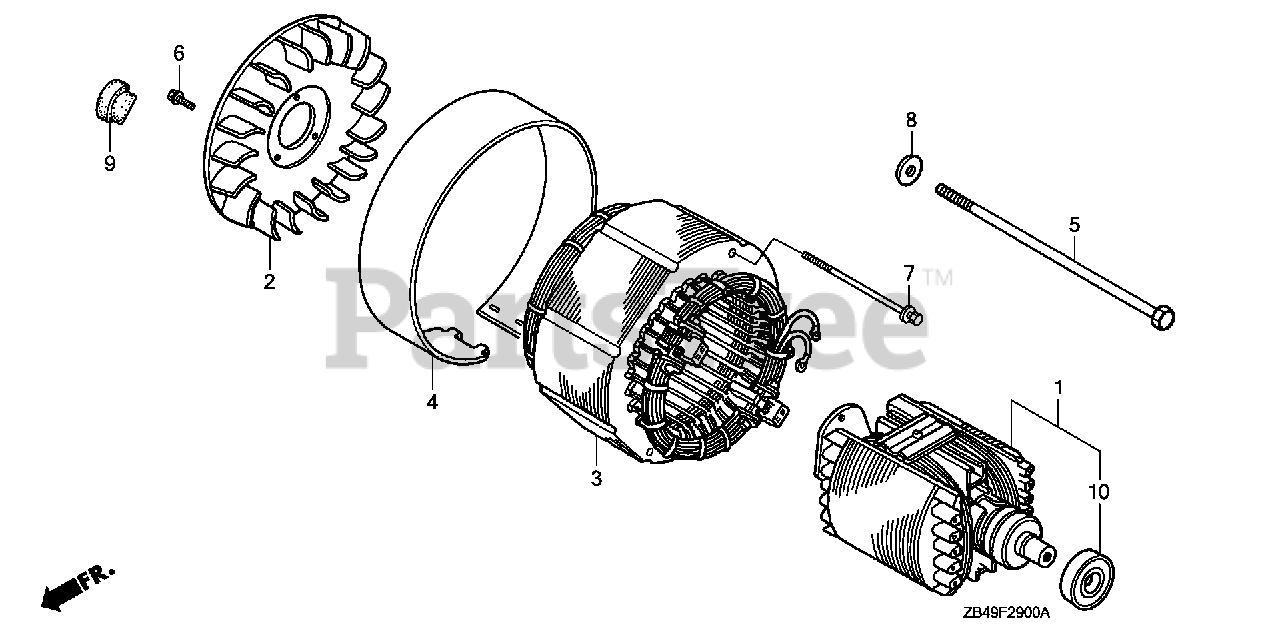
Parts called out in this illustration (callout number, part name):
2	FAN, GENERATOR COOLING
3	STATOR ASSY.
4	COVER, STATOR
5	BOLT, HEX. (10X210)
6	SCREW, TAPPING (5X14)
7	BOLT-WASHER (5X155)
8	WASHER (10.5MM)
9	GROMMET, CRANKCASE
10	BEARING ASSY. (6204)
